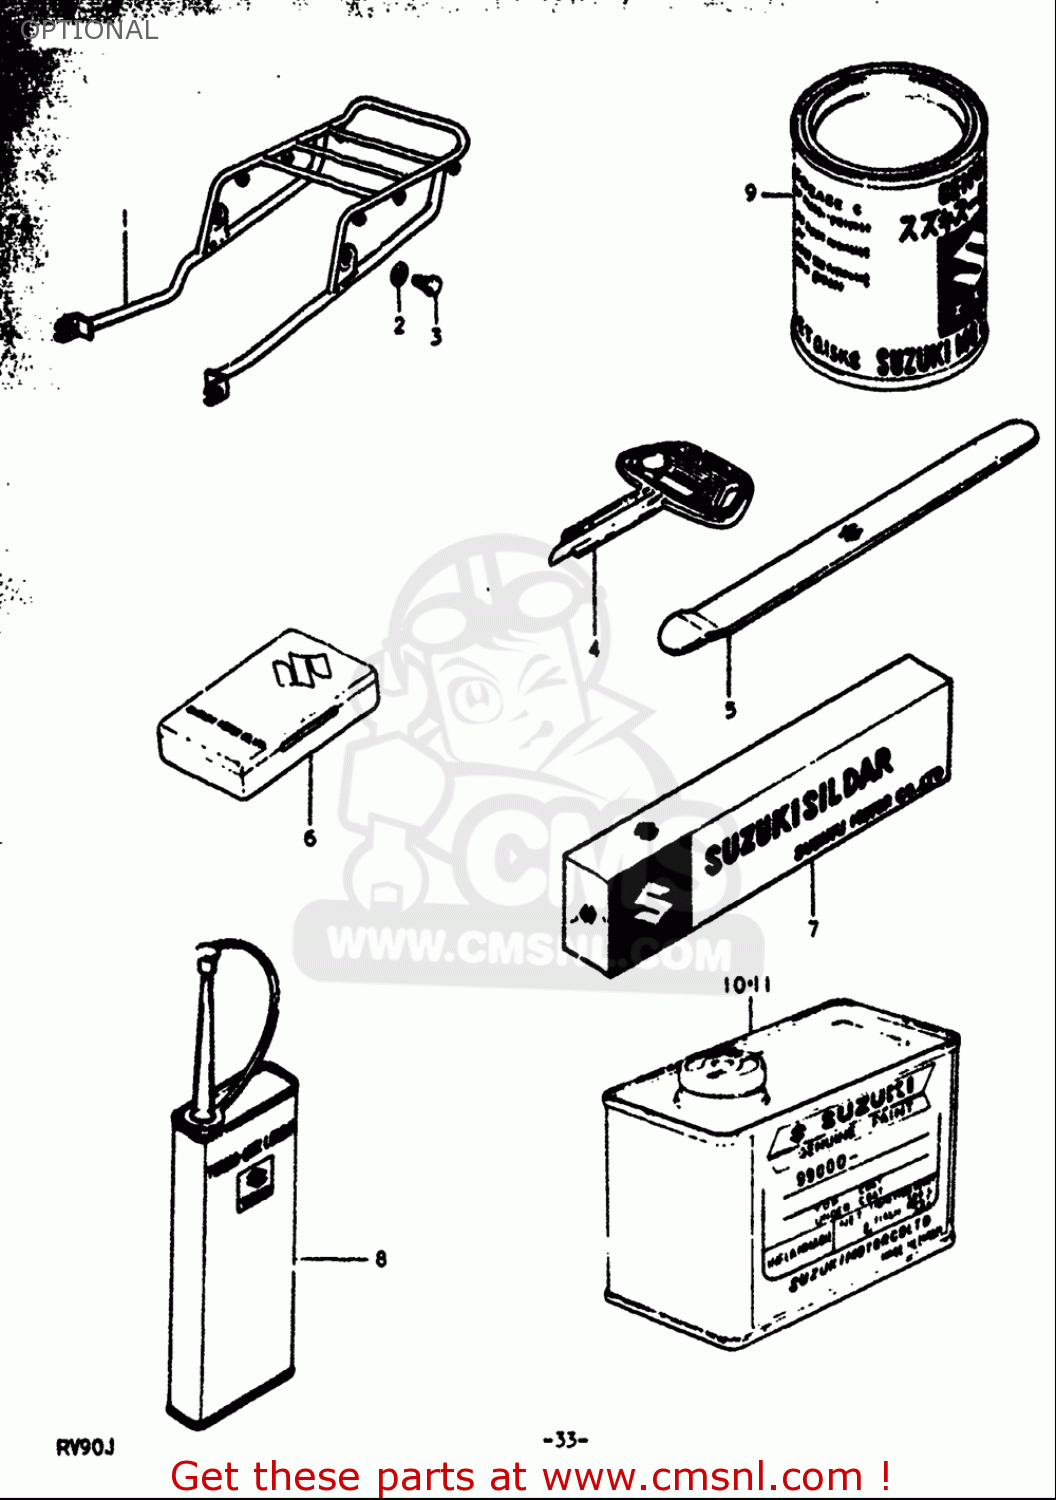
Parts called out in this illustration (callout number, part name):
2	WASHER,LOCK
3	BOLT
5	LEVER,TIRE
8	THREAD LOCK NO.1401 CLEAR 200G
9	GREASE(C)EP2 LITHIUM 150G
